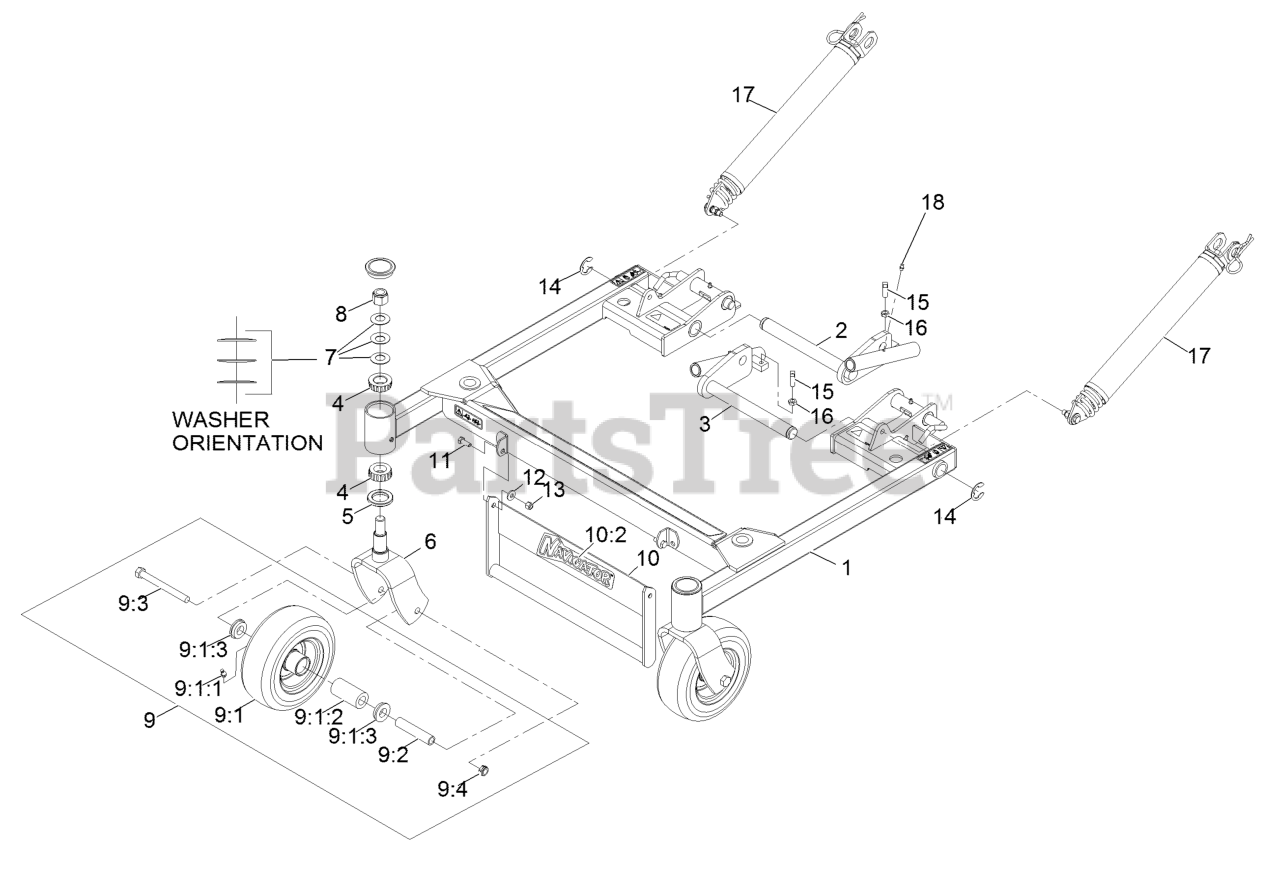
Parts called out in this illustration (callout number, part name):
1	DECK SUPPORT ASM
2	PIVOT-DECK, RH
3	PIVOT-DECK, LH
4	Cone-Bearing Tapered Roller
5	SEAL-GREASE
6	FORK-CASTER
7	WASHER-BELLVILLE
8	NUT-LOCK, NI
9	ASM,FF CASTER WHEEL W/AXL
9:1	ASM,WHEEL,TIRE & BRGS 8X3
9:1:1	FITTING-GREASE
9:1:2	BEARING-ROLLER, STRAIGHT
9:1:3	BUSHING
9:2	SPACER-CASTER, FRONT
9:3	SCREW-HH
9:4	NUT-HEX
10	ASM,DECK LIFT HANDLE W/DE
10:2	DECAL,NAVIGATOR MODEL
11	SCREW-HH
12	WASHER-SPRING
13	NUT-LOCK, NI
14	RING-SNAP
15	SCREW-SET, SQH
16	NUT-JAM
17	LIFT ASSIST SPRING ASM
18	FITTING-GREASE
